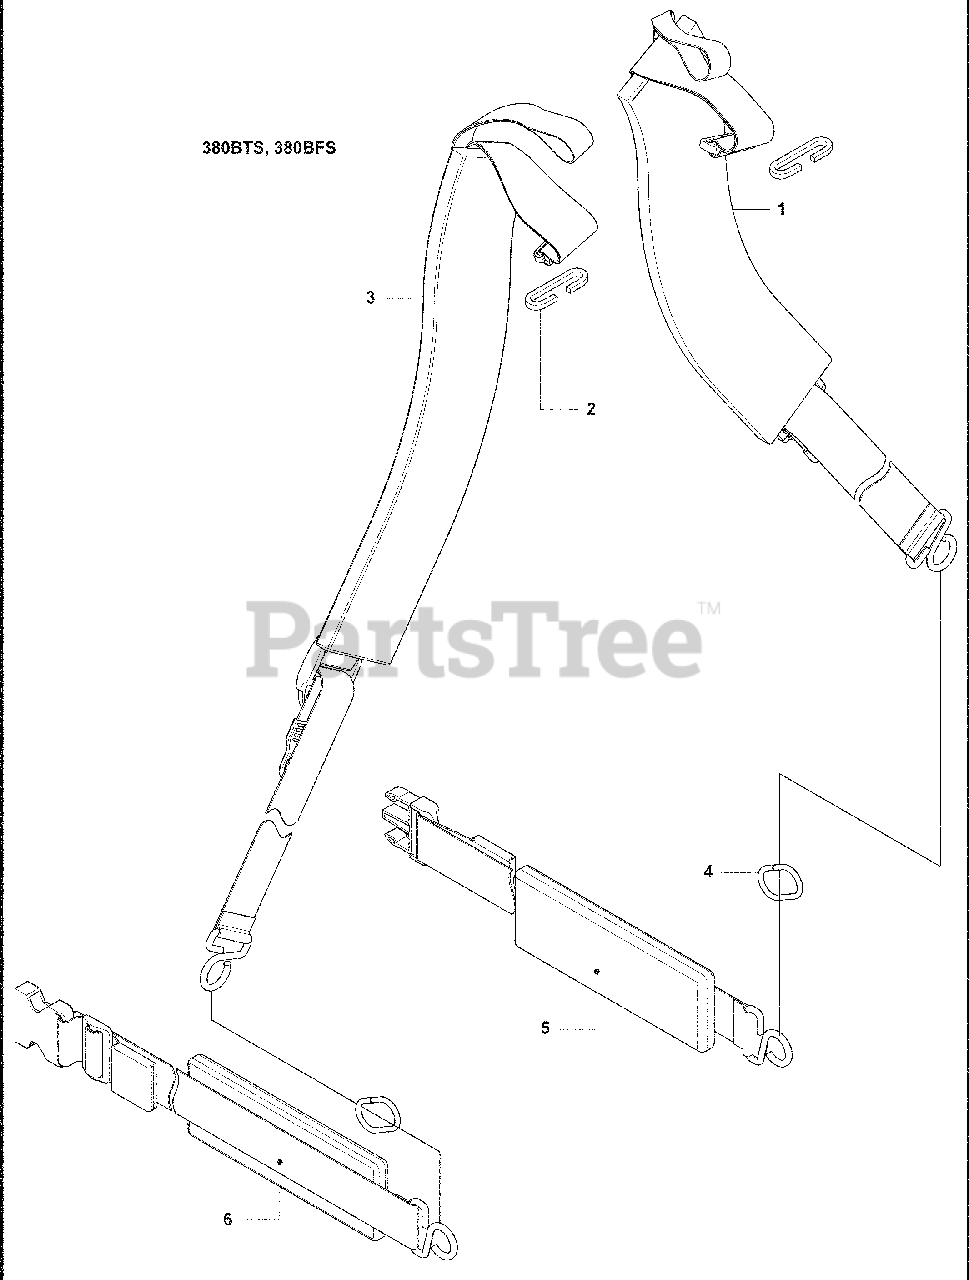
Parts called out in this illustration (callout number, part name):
1	Shoulder Strap, RH
3	Shoulder Strap, LH
4	Ring
5	Shoulder Strap, RH
6	Shoulder Strap, LH
